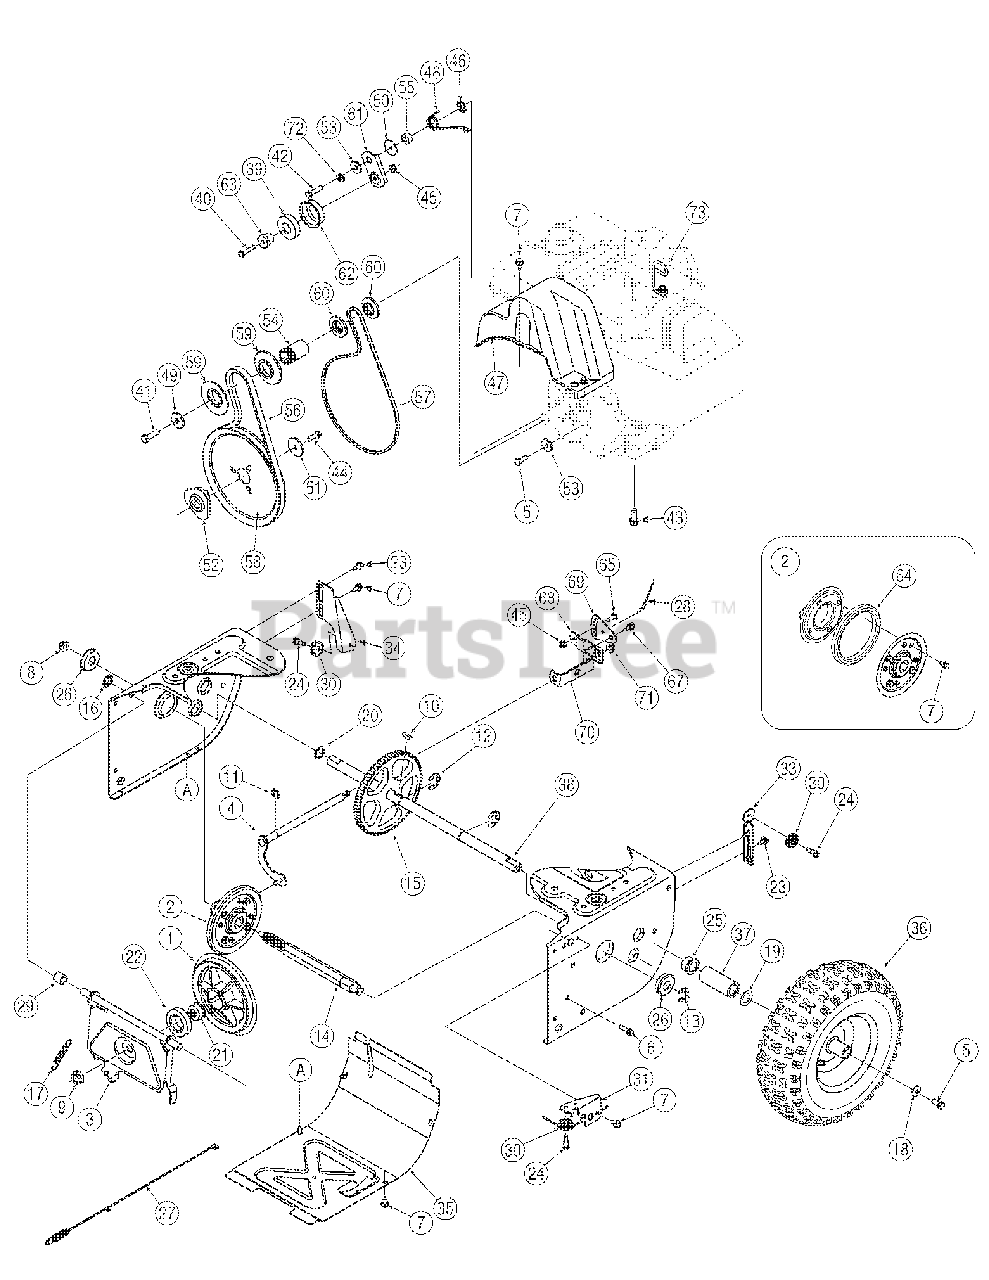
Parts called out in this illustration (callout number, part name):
1	Disc, Friction Wheel
2	Friction Wheel Assembly, 5.5 OD
4	Shift Assembly, Rod
5	Hex Screw, 5/16-24, .750, Gr5
6	Screw, 1/4-20, 1.000
7	Screw, 1/4-14 x .625
8	Nut, Flange Lock, 3/8-16,
9	Nut, Jam Lock, 5/8-18, Gr5, Nylon
10	Key, Hi Pro, 3/16 x 3/4 Dia.
11	E-ring, .500 Dia.
12	E-ring, Retaining, .875 Dia.
13	E-ring, .750 Dia.
14	Hex Shaft, .8125, 7-Tooth
15	Gear, 80-Tooth
16	Speed Nut, .500
17	Extension Spring
18	Washer, Bell, .340 x .872 x .060
19	Washer, Flat, .793 x 1.24 x .060
20	Washer, Flat, .75 x 1.00 x .060
21	Pin, Friction Disc
22	Ball Bearing, 30 x 55 x 13
23	Screw, Shoulder, .37 x .105, 1/4-20
24	Screw, 1/4-28, .375
25	Bearing, Hex Flange x .75 ID
26	Bearing, Ball, 17 x 40 x 12
27	Clutch Cable, Wheel, 44.95"
28	Clutch Cable, Auger, 47.23"
29	Spacer, .508 ID x .75 OD x .68
30	Roller, Cable
36	Valve Only
37	Spacer, 1.25 x .75 x 3.0
38	Axle, .75 x 22"
39	Ball Bearing
40	Hex Screw, 1/4-20, 1.25, Gr5
41	Hex Screw, 3/8-24, 1.25,
42	Hex Screw, 5/16-24, 1.25,
43	Screw, Sems, 3/8-16, 1.00
44	Hex Screw, 5/16-24, .875, Gr8
45	Nut, Flange Lock, 1/4-20, Nylon
46	Nut, Push-on, .25 Dia.
47	Cover, Belt
48	Spring, Torsion, .850 ID x .354
49	Washer, Flat, .406 x 1.25 x .157
50	Washer, Flat, .330 x 1.25 x .06
51	Washer, Flat, .34 x 1.50 x .150
52	Pulley, Adap, .75 Dia W/dd
53	Spacer, Shoulder
54	Spacer, .875 ID x 1.185
55	Spacer, .340 x .750 x .360
56	Belt, Auger Drive
57	Belt, Wheel Drive
58	Pulley, Auger Drive, 8.1 x .5
59	Pulley, Half, V x 2.600 OD
60	Pulley, Half, 1/4-V x 1.5
61	Idler Bracket, Wheel Drive
62	Sleeve, Bearing Idler
63	Spacer, Shoulder, .26 x .79
64	Rubber, Friction Wheel, 5.5
65	Hex Screw, 1/4-20, .620, Gr5
66	Spring, Torsion, .750 ID x .968
67	Screw, Shoulder, .37 x .105, 1/4-20
68	Bracket, Shift Spacer
71	Nut, Flange Lock, 5/16-18, Nylon
72	Washer, Lock, 5/16
73	Cable Control Wire
